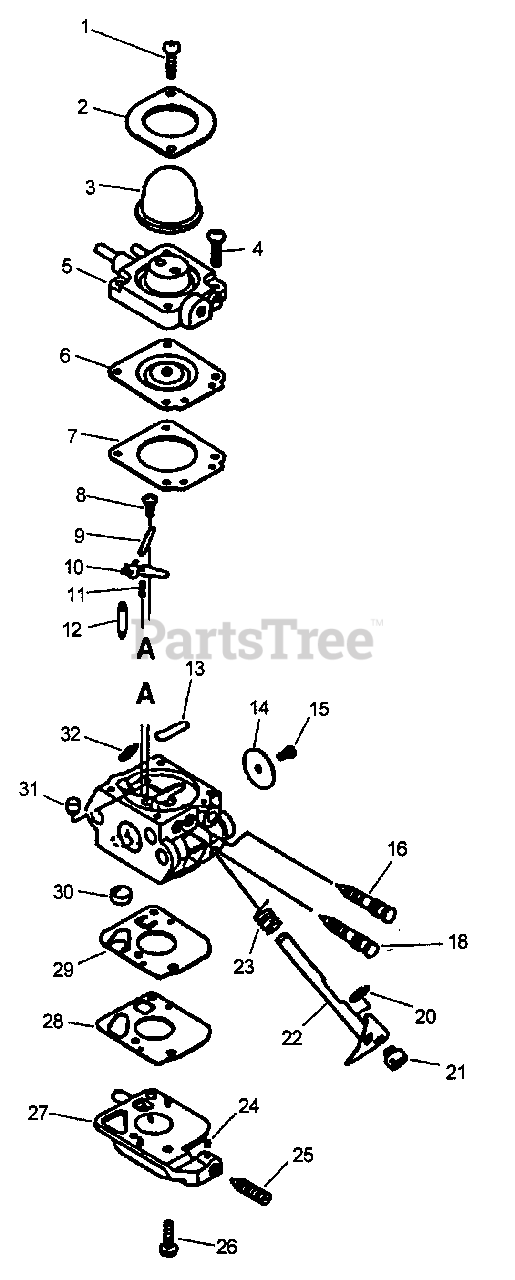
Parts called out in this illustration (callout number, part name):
1	SCREW, RETAINER
2	RETAINER, PURGE BULB
3	BULB, PURGE
4	SCREW, PURGE BASE
5	BASE, PURGE
6	DIAPHRAGM, METERING
7	GASKET, METERING DIAPHRAGM
8	SCREW, METERING LEVER PIN
9	BASE, PURGE
10	BASE, PURGE
11	BASE, PURGE
12	BASE, PURGE
13	BASE, PURGE
14	VALVE, THROTTLE
16	NEEDLE - LOW SPEED
18	NEEDLE - HIGH SPEED
20	RING, RETAINING
22	SHAFT, THROTTLE
23	SPRING, RETURN
24	PIECE, FRICTION
25	SCREW, IDLE ADJUST
26	SCREW, PUMP COVER
27	BASE, PURGE
28	GASKET, FUEL PUMP
29	DIAPHRAGM, PUMP
30	BASE, PURGE
31	NOZZLE, CHECK VALVE
32	RING, RETAINING
A	REPAIR KIT
B	DIAPHRAGM/GASKET KIT
